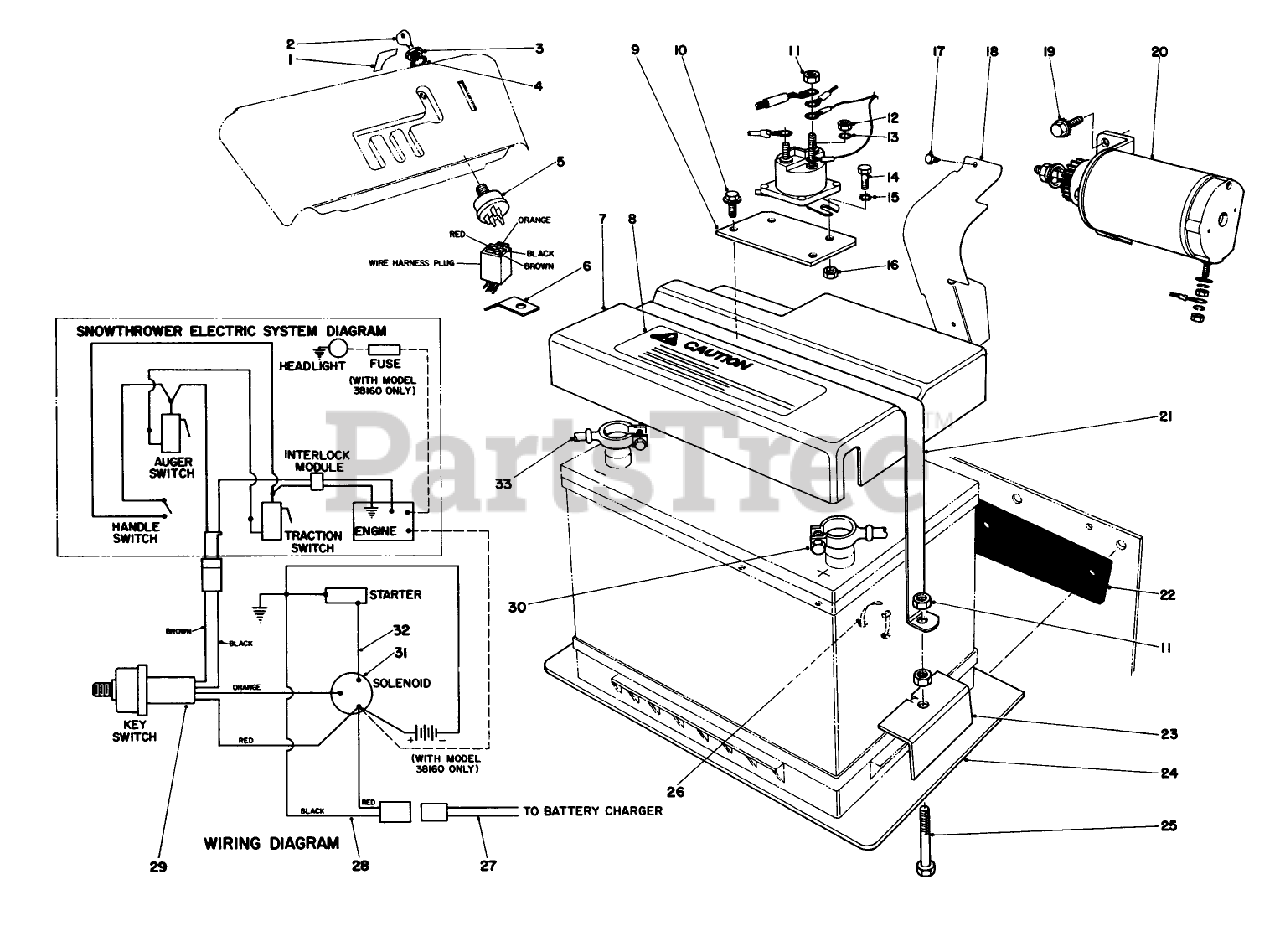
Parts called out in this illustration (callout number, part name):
3	NUT-HH
4	WASHER-LOCK
8	0630 Decal-Caution
10	SCREW-HWH
11	NUT-HEX
12	NUT-HEX
13	WASHER-LOCK, INT
14	SCREW-HH
15	WASHER-LOCK/EXT
16	19 Nut
18	BRIGGS 280265
19	5/16-18X3/4 HX HD SEM
20	Starter Motor Pinion Assy.
25	SCREW-HH
26	TIE-CABLE
27	MALE WIRE ASM
30	BATT-SOLENOID CABLE
31	SOLENOID
